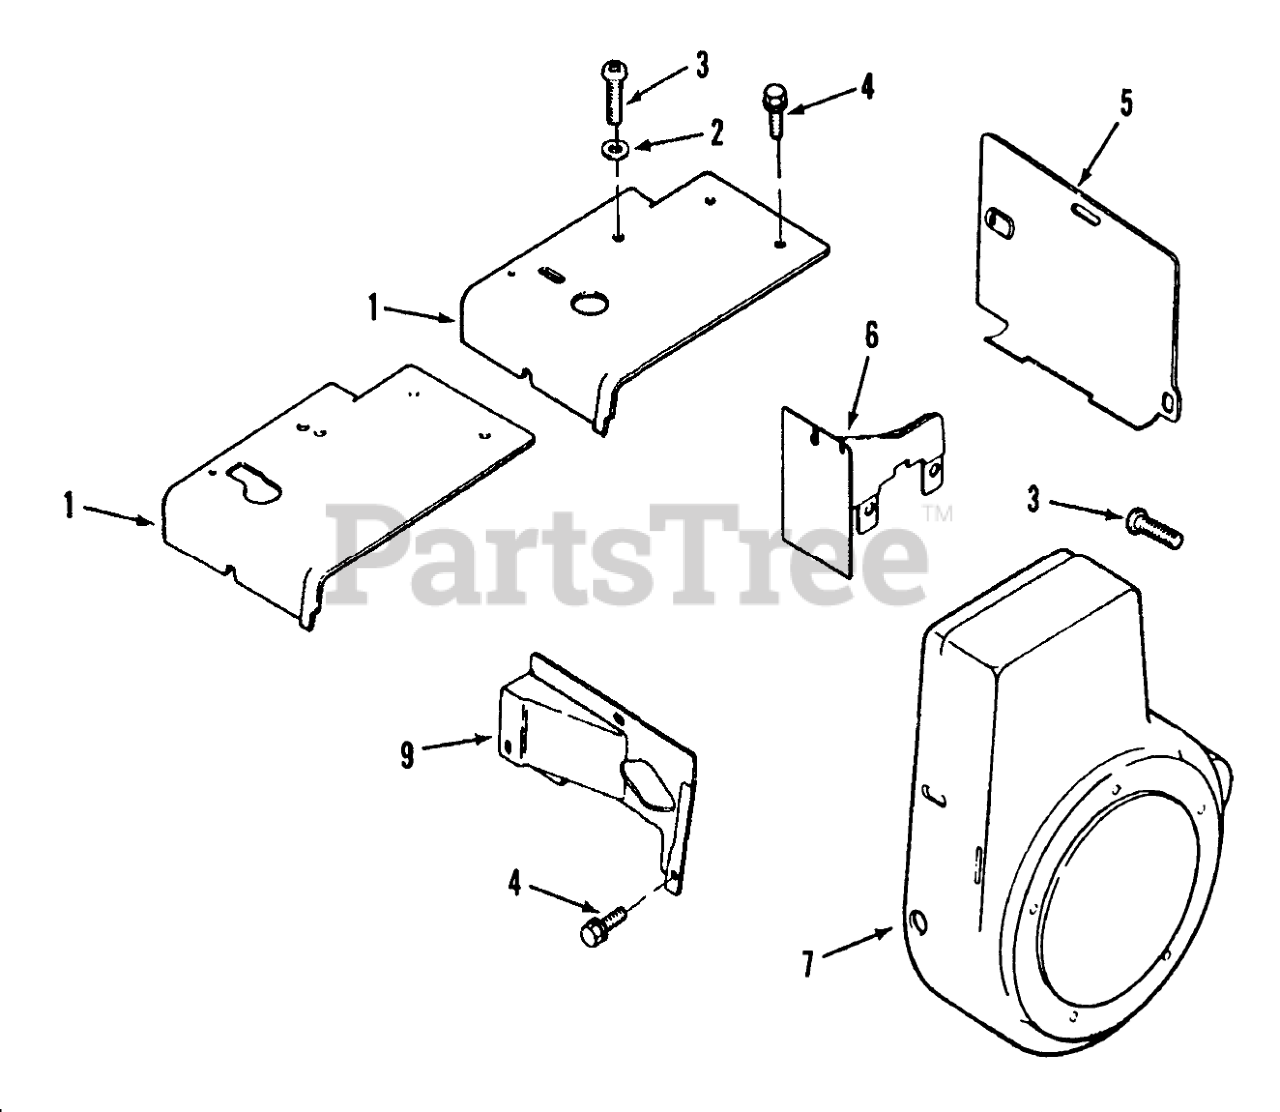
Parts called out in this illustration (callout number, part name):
1	Baffle-Head
2	Washer
3	Screw-Pozidriv T.H.
4	Screw Hex Hd
5	Cylinder Baffle
6	Baffle-Inner
7	Blower Housing
9	Baffle-SideAir
